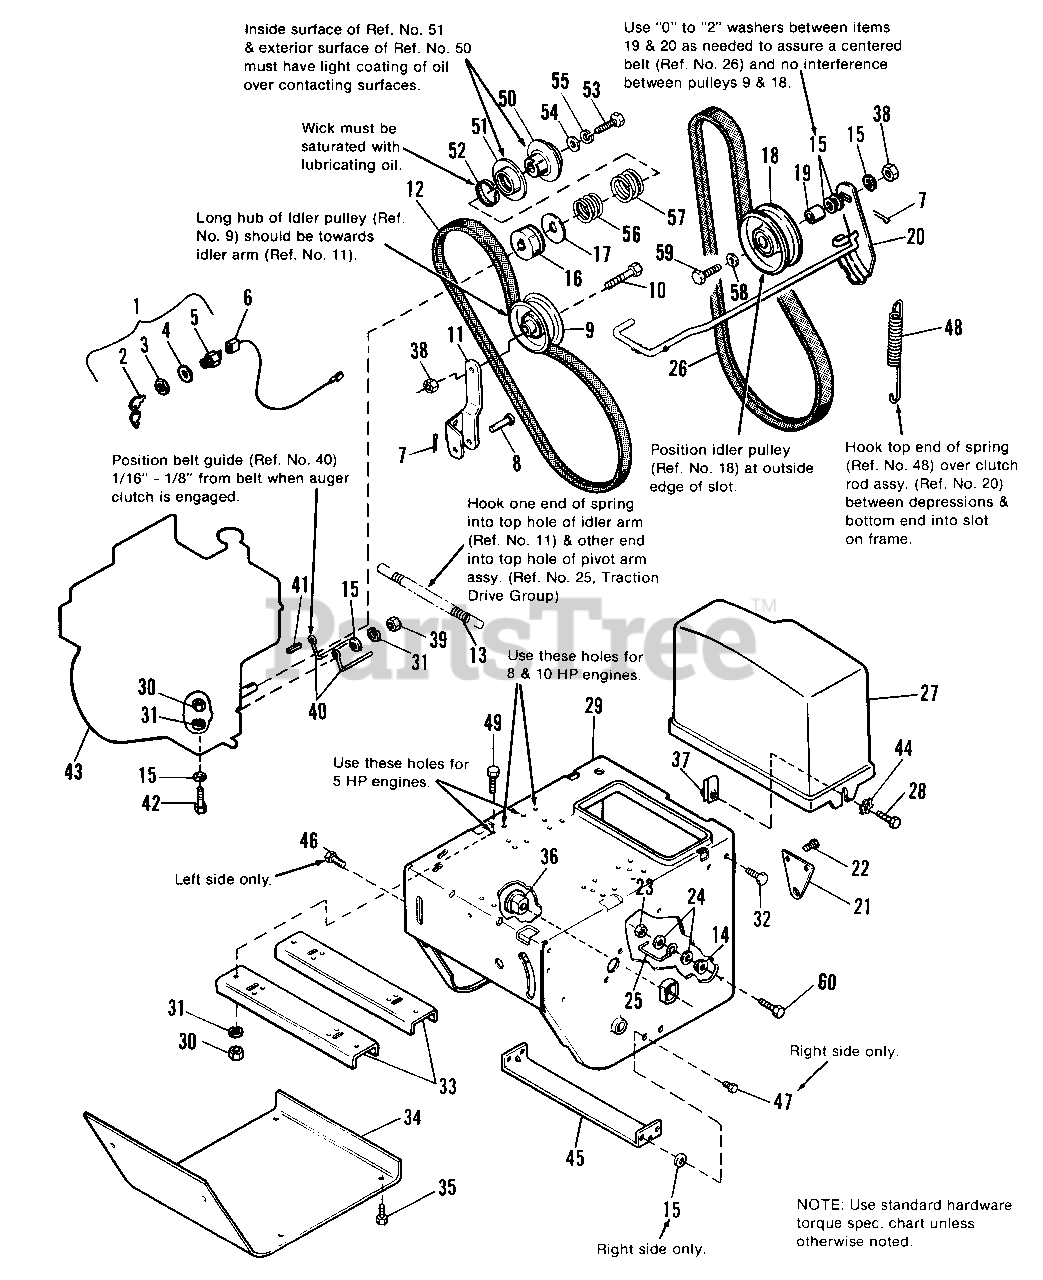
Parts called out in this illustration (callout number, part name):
1	SWITCH, Key (Inc. Ref. Nos. 2, 3, 4 & 5)
3	NUT, Hex, 5/8-32
4	LOCKWASHER, Int. 5/8
6	WIRE, Ground
7	PIN, Cotter, 1/8 x 3/4
8	PIN
9	PULLEY, Idler
10	CAPSCREW, Hex Hd., 3/8-16 x 1-1/2
12	BELT, Traction
13	SPRING, Idler
14	NUT, Hex, Whizlock 5/16-18
15	WASHER, Flat, 5/16
16	PULLEY, Traction
17	WASHER, Thrust
18	PULLEY ASSY.
20	CLUTCH ROD ASSY.
21	BRACKET, Clutch Pivot
22	SCREW, Taptite, 1/4-20 x 1/2
23	NUT, Hex, Centerlock, 5/16-18
24	WASHER, 11/32 x 3/4
26	BELT, Auger Drive
27	GUARD, Belt
28	SCREW, Truss Hd., 5/16-18 x 3/4
29	FRAME, Main
30	NUT, Hex, 5/16-18
31	LOCKWASHER, 5/16
32	CAPSCREW Whizlock, 5/16-18 x 3/4
33	BRACKET, Engine Mounting
34	COVER, Bottom
35	SCREW, Taptite, 1/4-20 x 3/8
36	BUSHING, Axle
37	NUT, Pal, 5/16-18
38	LOCKNUT, Jam, 3/8-16
39	CAPSCREW, Hex. Hd., 5/16-24 x 3/4
40	BELT GUIDE
41	KEY, Parallel, 3/16 x 13/16 x 7/8
42	CAPSCREW, Hex Hd., 5/16-18 x 2
43	ENGINE, Tecumseh, 5 H.P. ENGINE, Tecumseh, 8 H.P. ENGINE, Tecumseh, 10 H.P.
44	LOCKWASHER, Ext. Tooth, 5/16
45	SUPPORT, Tie Bar
46	SCREW, Taptite, 5/16-18 x 3/8 (left side only)
47	SCREW, Taptite, 5/16-18 x 3/4 (right side only)
48	SPRING, Extension
49	CAPSCREW, Hex Hd., 5/16-18 x 3/4
50	PULLEY, Half, Drive
51	PULLEY, Half
53	CAPSCREW, Hex Hd., 3/8-24 x 2
54	WASHER, 13/32 x 1
55	LOCKWASHER, Spring, 3/8
56	SPRING, Compression (1691368, 1691370 only)
56	SPRING, Compression (1691371, 1691716 only)
57	SPRING, Compression (1691370, 1691371, 1691716 Only)
58	WASHER, Flat, 3/8
59	CAPSCREW, Hex Hd., 3/8-16 x 1-3/4
60	CAPSCREW, Whizlock, 5/16-18 x 1-1/4
